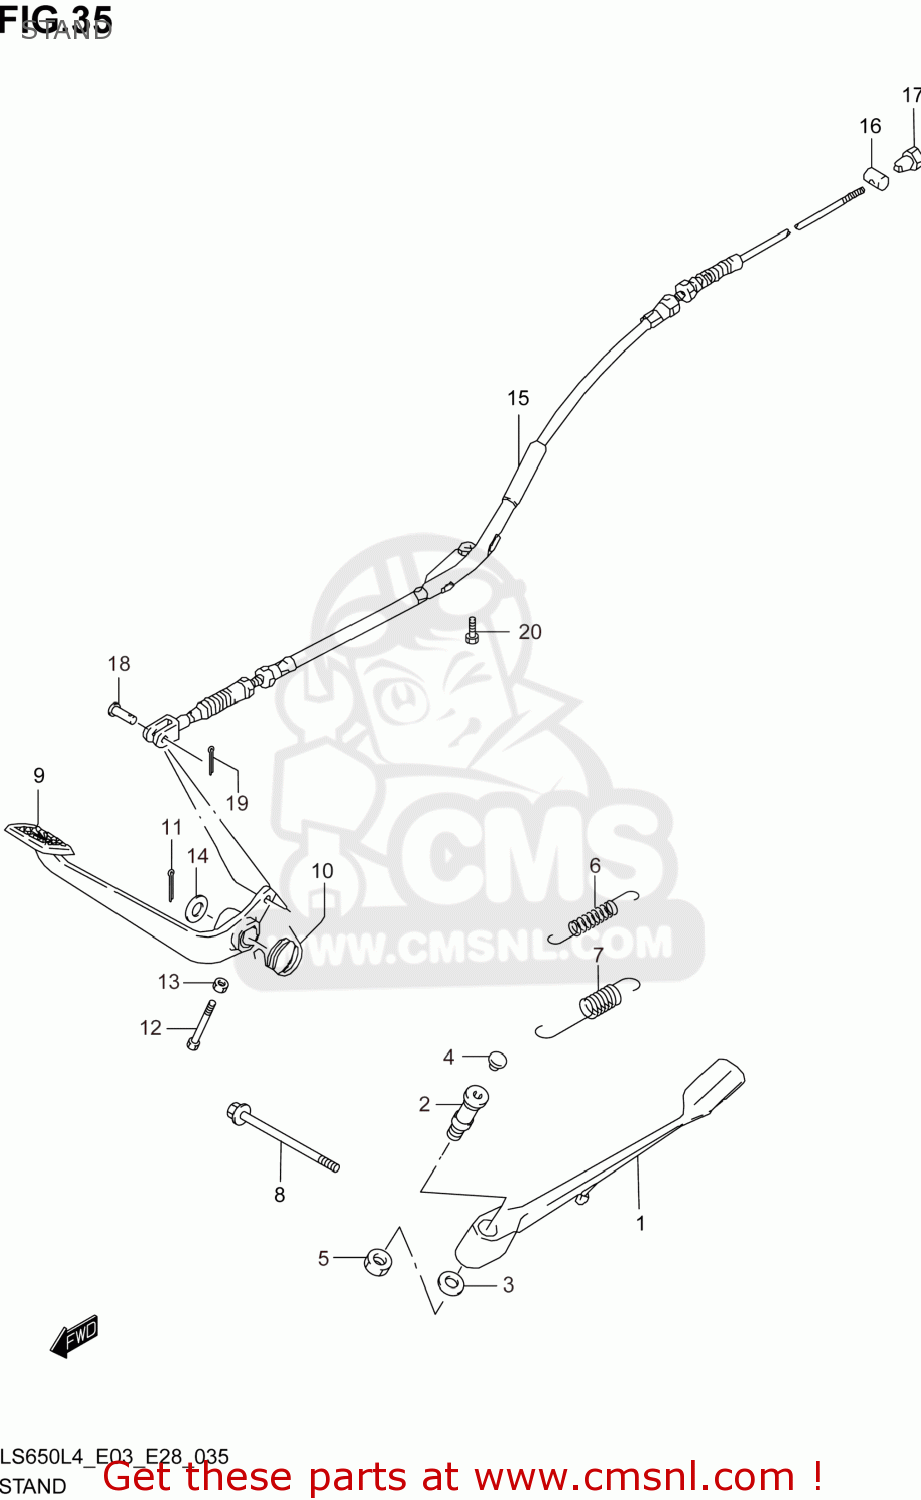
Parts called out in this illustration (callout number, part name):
1	STAND,PROP
2	BOLT,PROP STAND
3	SHIM(15X24X0.5)
4	CAP,HANDLE HOLDER BRACKET BOLT
5	NUT
6	SPRING
7	SPRING
8	BOLT(10X105)
9	PEDAL,BRAKE
10	SPRING
11	PIN
12	BOLT(6X31)
13	NUT
14	WASHER(16.5X22X1)
15	CABLE,RR BRAKE
16	PIN(13X18)
17	NUT
18	PIN(L:17.5)
19	PIN
20	BOLT
